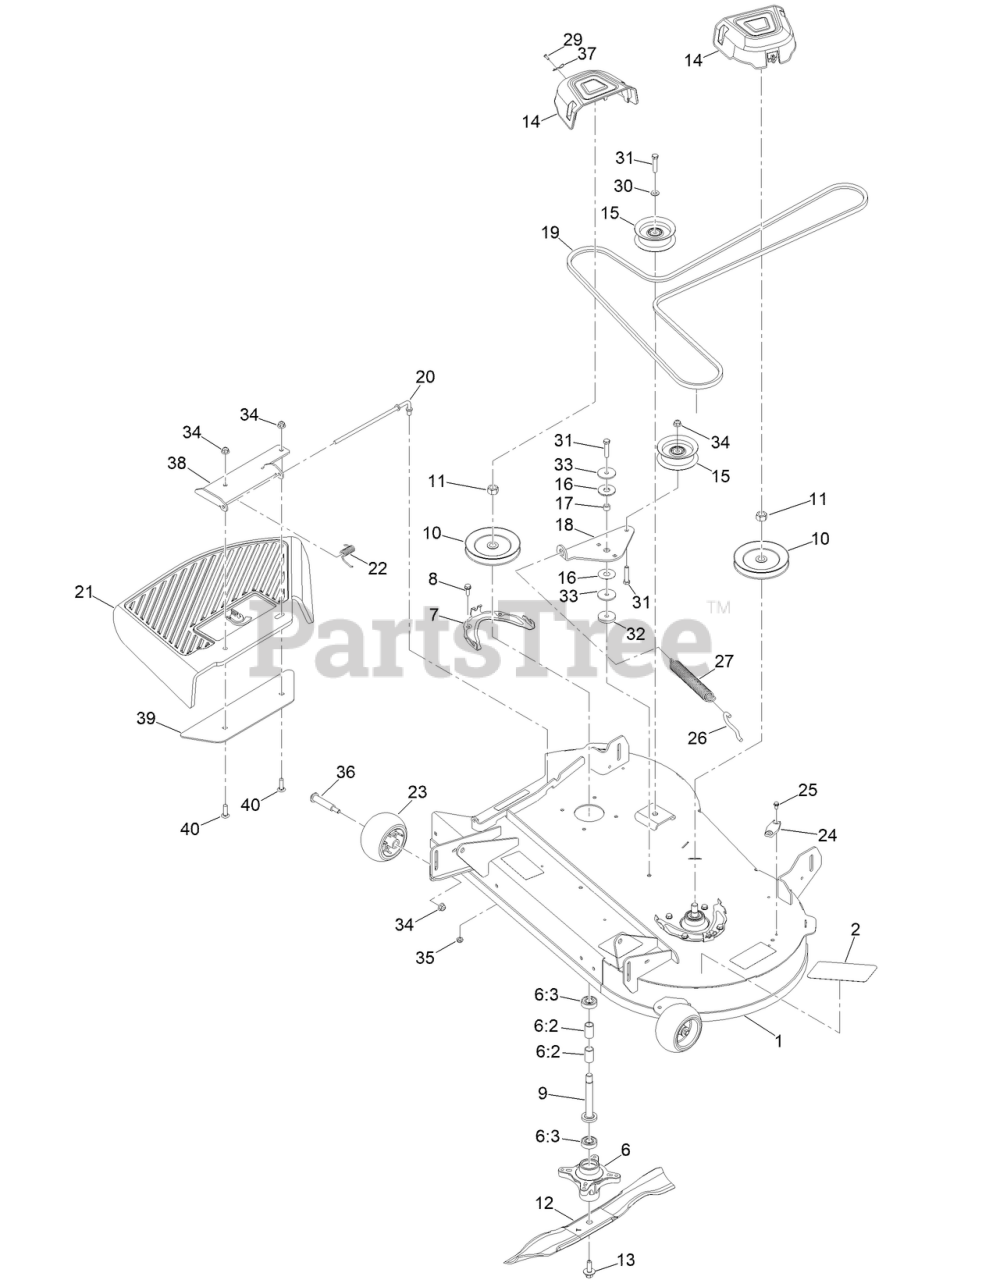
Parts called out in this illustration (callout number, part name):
1	42 IN DECK DECAL ASM
2	DECAL-DECK 42IN
6	SPINDLE ASM
6:2	SPACER
6:3	BEARING-BALL
7	BRACKET-COVER, BELT
8	SCREW-TAPTITE
9	SHAFT-SPINDLE
10	PULLEY
11	NUT-HEX
12	BLADE-21.6 IN
13	BOLT-BLADE, SEMS
14	COVER-BELT
15	PULLEY-IDLER, FLAT
16	WASHER-FRICTION, COMPOSITE
17	SPACER
18	ARM-IDLER
19	V-BELT
20	ROD-PIVOT
21	DEFLECTOR-DISCHARGE
22	SPRING-TORSION
23	ROLLER-SCALP, ANTI
24	COVER-WASHOUT PORT
25	SCREW-HWH
26	HOOK-SPRING, RETURN
27	SPRING EXTENSION
29	SCREW
30	WASHER-FLAT
31	SCREW-HH
32	WASHER-PLAIN
33	WASHER-REBOUND
34	NUT-HF, NI
36	BOLT-SHOULDER
37	PIN-HAIR
38	BRACKET-DISCHARGE, TOP [GRAY]
39	SUPPORT-DEFLECTOR [GRAY]
40	SCREW-CARR
